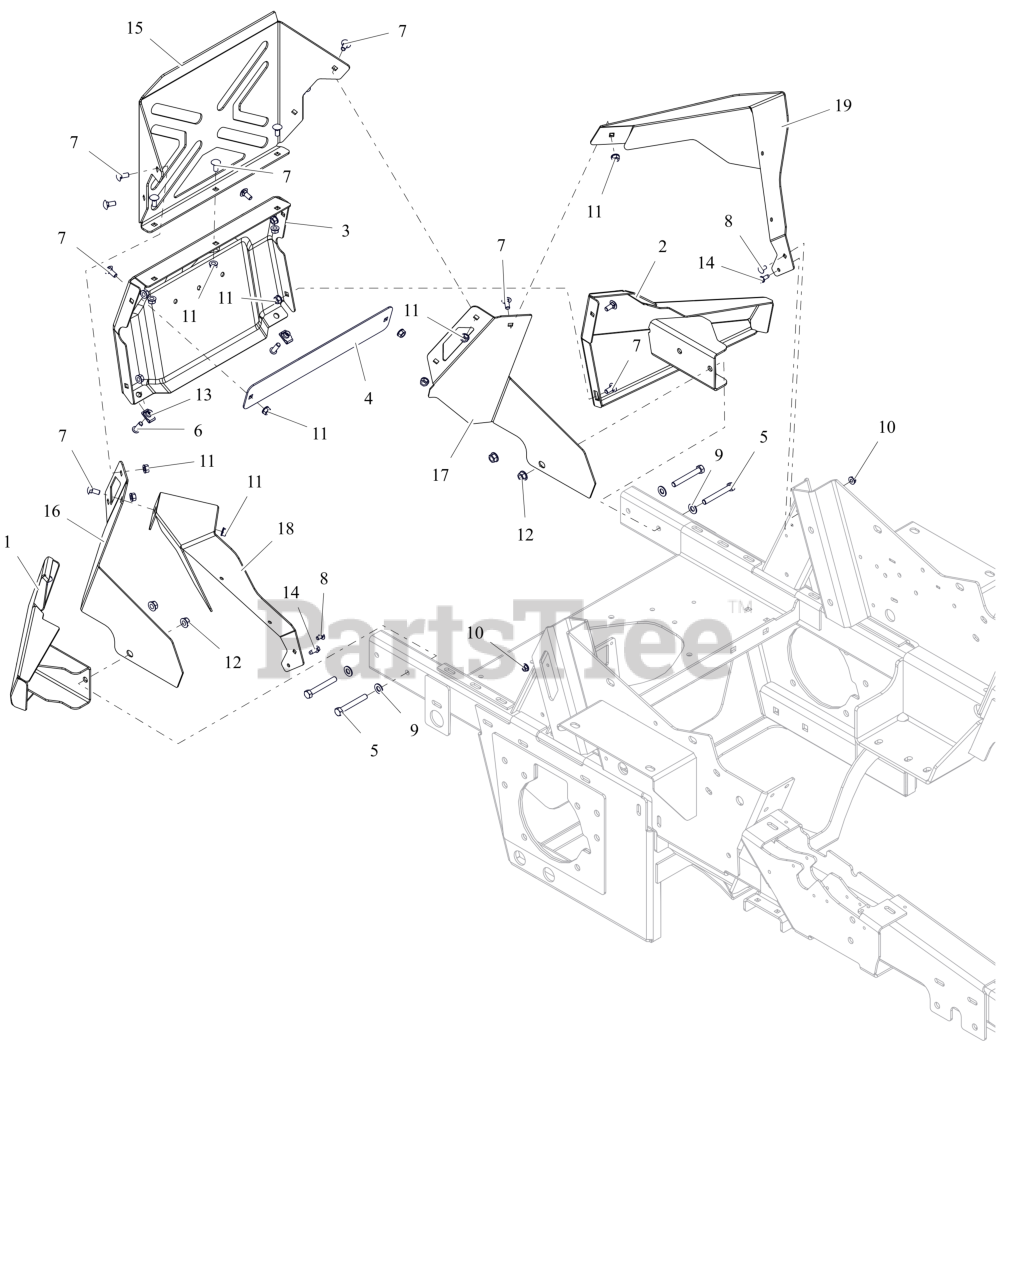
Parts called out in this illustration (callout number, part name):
1	WLDMT, RIGHT REAR BUMPER WING (RED) W/ SAFETY DECALS
2	WLDMT, LEFT REAR BUMPER WING (RED) W/ SAFETY DECALS
3	BUMPER, COMMERCIAL REAR
4	PLATE, BACKER (BLACK)
5	BLT, HEX .38-16X2.75 G5 ZCC
6	BLT,SHCS-BTN .31-18X1.00 ZCC
7	BLT,RHSN .31-18X.75 G5 ZCC
8	BLT, RHSSN.25-20X.500 G5 ZCC
9	WSHR,FLT .406X.812X.065 ZCC
10	NUT-LK-CTR-FLG .25-20 ZC120
11	NUT,LK-CTR-FLG .31-18 GF ZCC
12	NUT-LK-CTR-FLG .375-16 GF ZCC
13	NUT-CLIP RETAINER 5/16-18X.56
14	SCR,TAP .25-20X.625 HWH ZCC
15	WRAP, REAR - CENTER (BLACK)
16	WRAP, REAR - RH (RED)
17	WRAP, REAR LH (RED)
18	WRAP, SIDE - RH (RED)
19	WRAP, SIDE - LH (RED)
